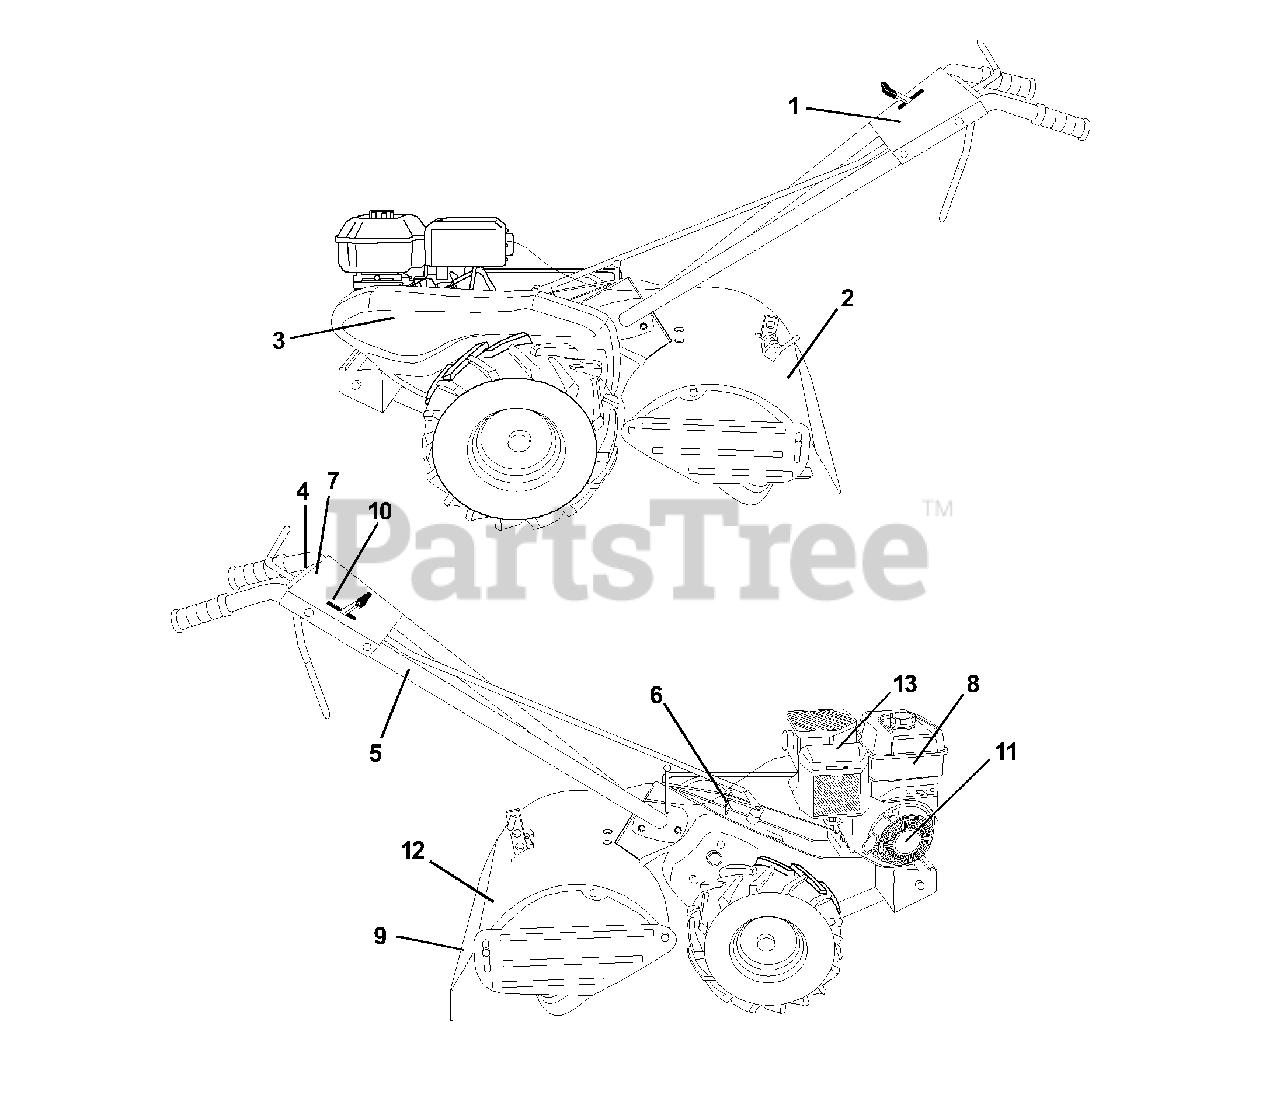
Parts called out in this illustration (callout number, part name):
1	Decal, Logo
2	Decal, Logo
3	Decal, Logo
4	Decal, Instruction, Tilling
5	Decal, Hand Placement
6	Decal, Shift Indicator
7	Decal, Pnl Cntrl Reverse
8	Decal, OHV.N-I/C
9	Decal, Warning, Rotating Tines
10	Decal, Throttle
11	Decal, Rewind Intek
12	Decal, Warning Till
13	Decal, B&S Tiller
